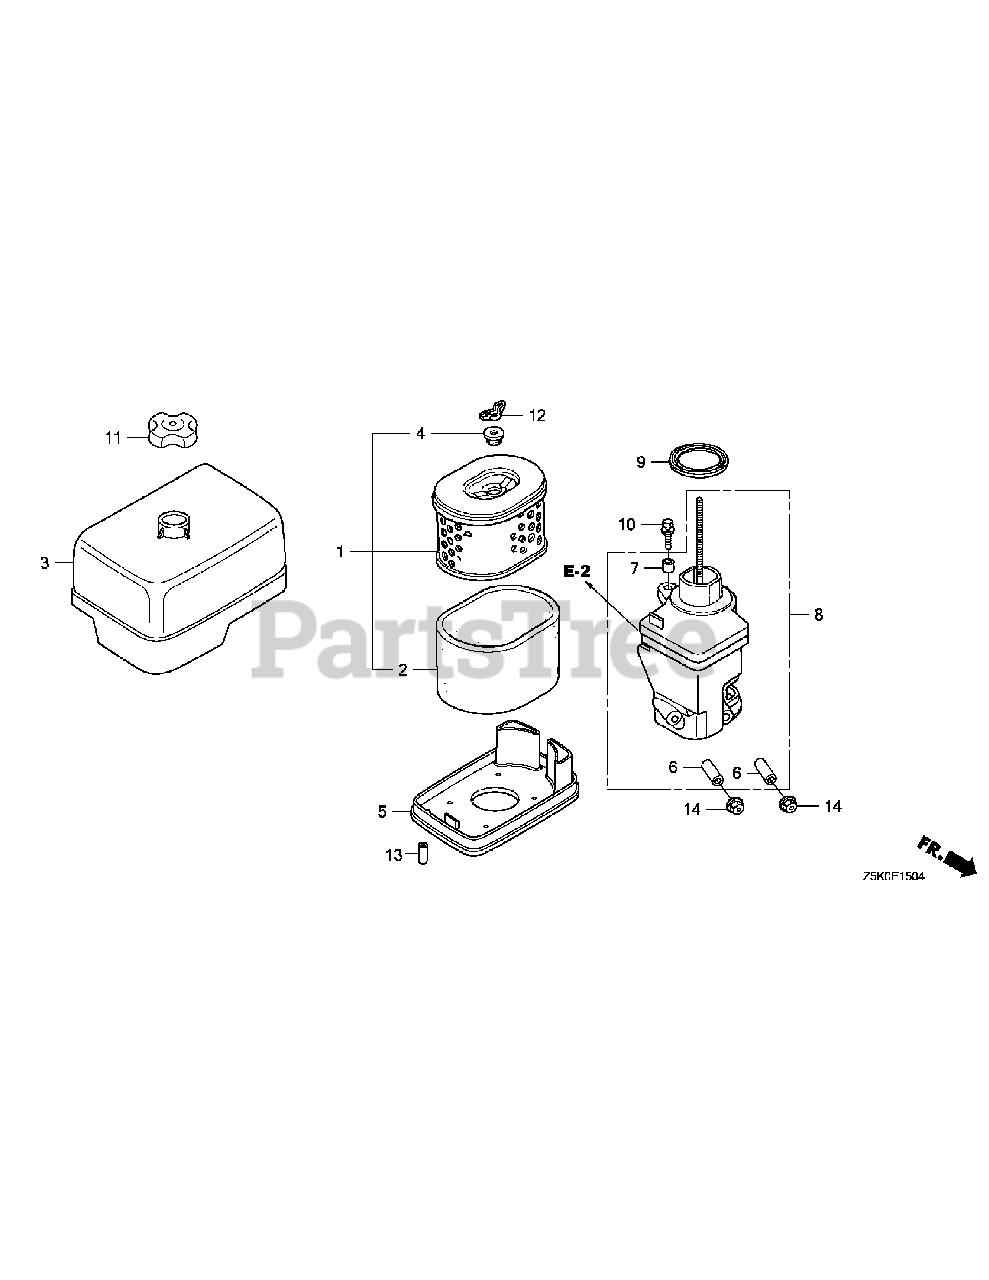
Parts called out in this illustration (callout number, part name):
1	Element, Air Cleaner(Dual)
2	Filter, Outer
3	Cover, Air Cleaner Case
4	Grommet, Air Cleaner
5	Nose, Silencer
6	Collar, Air Cleaner
7	Collar B, Air Cleaner
8	Elbow Comp., Air Cleaner
9	Packing, Air Cleaner Case
10	Bolt-Washer, 6X22
11	Nut, Air Cleaner Cover
12	Nut, Tool Box Setting
13	Cap, Sealing
14	Nut, Flange, 6Mm
